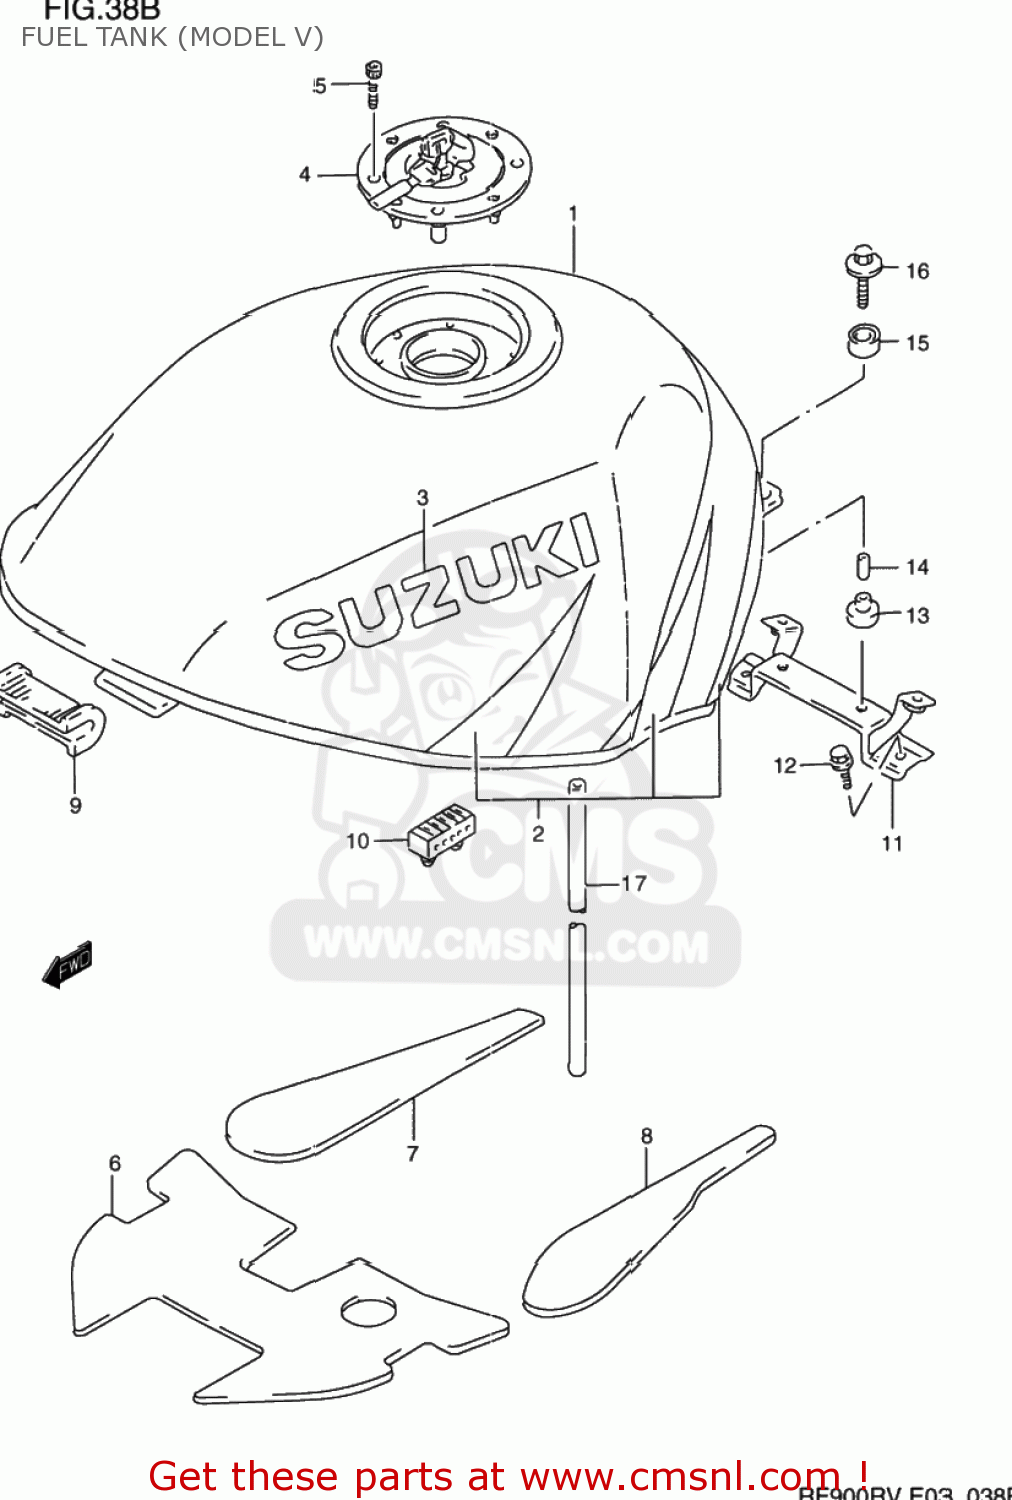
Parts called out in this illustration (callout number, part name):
1	TANK ASSEMBLY,FUEL
2	TAPE SET,FUEL TANK
3	EMBLEM,FUEL TANK
4	CAP SET,FUEL
5	BOLT(5X20)
6	SHIELD,FUEL TANK HEAT NO.1
7	SHIELD,FUEL TANK HEAT NO.2
8	SHIELD,FUEL TANK HEAT NO.3
9	CUSHION,FUEL TANK FR
10	CUSHION,SEAT(40X20X15)
11	BRACKET,FUEL TANK RR
12	BOLT
13	CUSHION
14	SPACER(6.5X9X18)
15	CUSHION
16	BOLT
17	HOSE(7X10.2X600)
